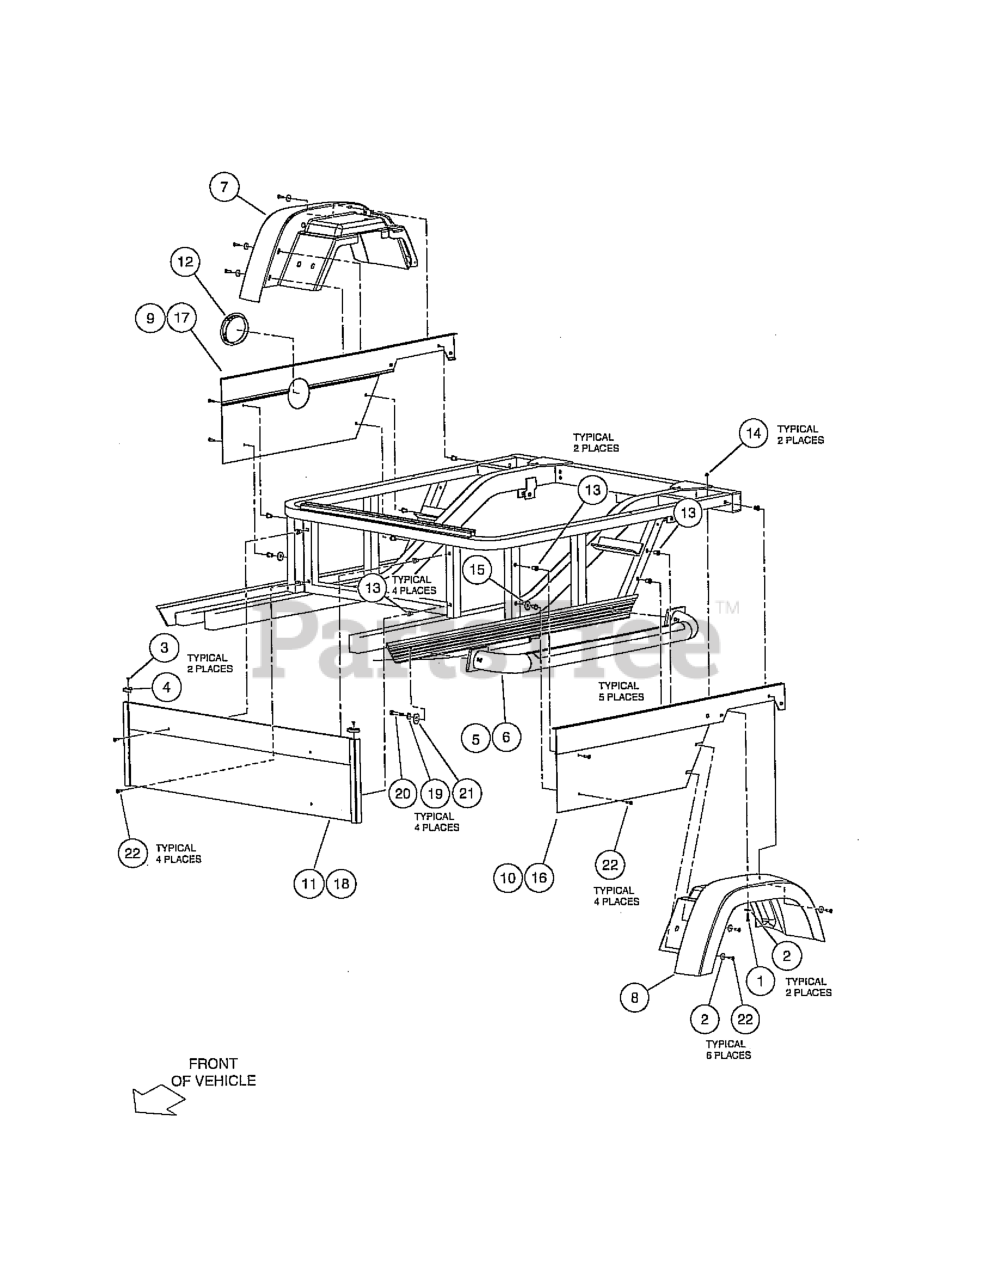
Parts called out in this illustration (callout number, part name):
4	CORNER CAP AWD
5	SIDE STEP BAR
6	SIDE STEP BAR
7	FENDER, RIGHT REAR
8	FENDER. LEFT REAR
9	PANEL, SIDE, WELDMENT, PASS
10	PANEL, SIDE, WELDMENT, DRV
11	PANEL, FRONT, WELDMENT
12	BEZEL, FUEL FILL
13	WELL NUT 1/4-20
14	NUT FLG, M6 X 1.0 NYLON
15	WASHER, M12 HARD REGULAR
18	FRONT PANEL ORANGE
19	WASHER,LOCK,HEL SP 3/8 REG
20	BOLT, 3/8-16 X 3.00 HEX HEAD
21	WASHER, 3/8 B FLAT
22	SCREW, 1/4-20 X 1.0 TRS HD MCH
